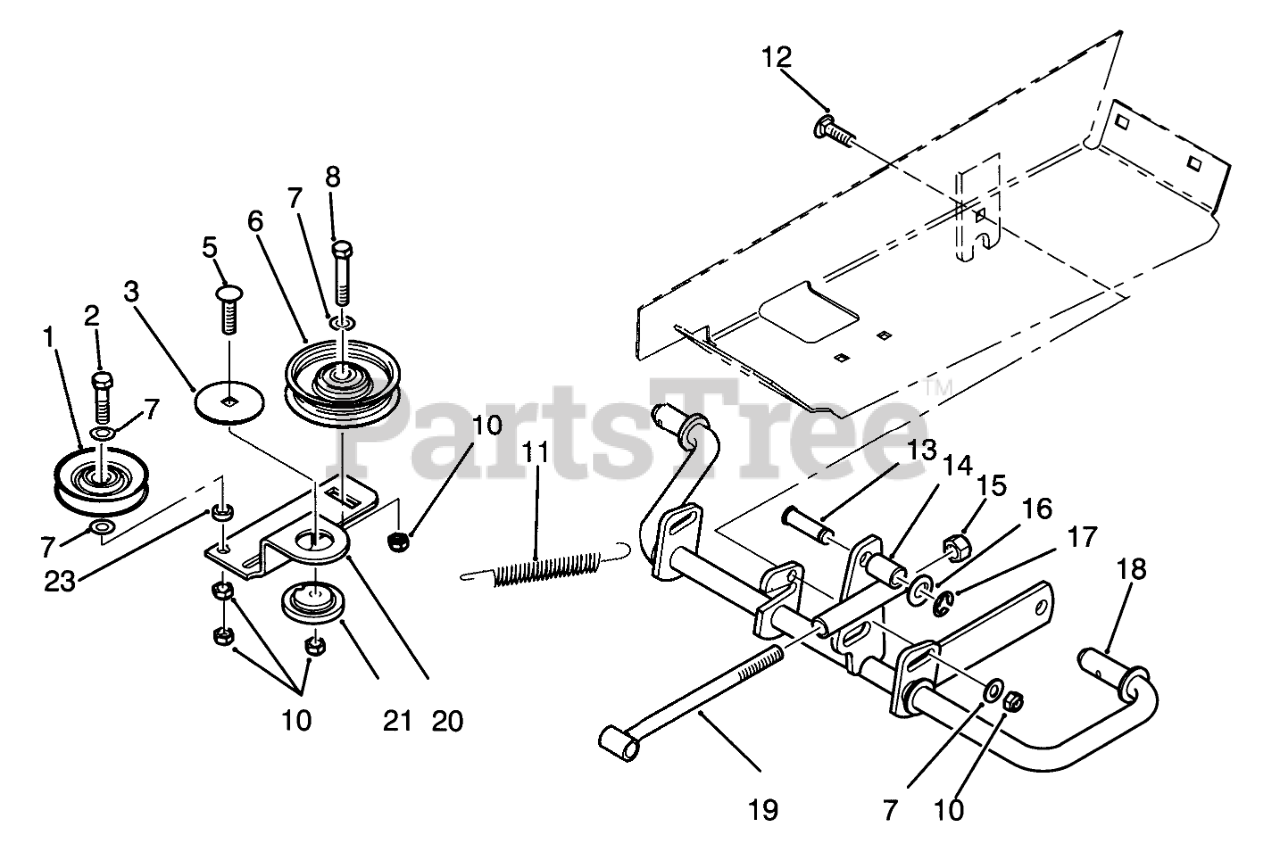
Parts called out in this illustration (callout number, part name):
1	Pulley
2	SCREW-HH
3	WASHER-BEARING
5	SCREW-CARR
6	Idler Pulley
7	WASHER-FLAT
8	SCREW-HH
11	SPRING - CLUTCH
12	BOLT-CARR
16	WASHER-FLAT
17	RING-RETAINING, EXTERNAL
18	Shaft
20	ARM-IDLER
21	BUSHING
23	SPACER
